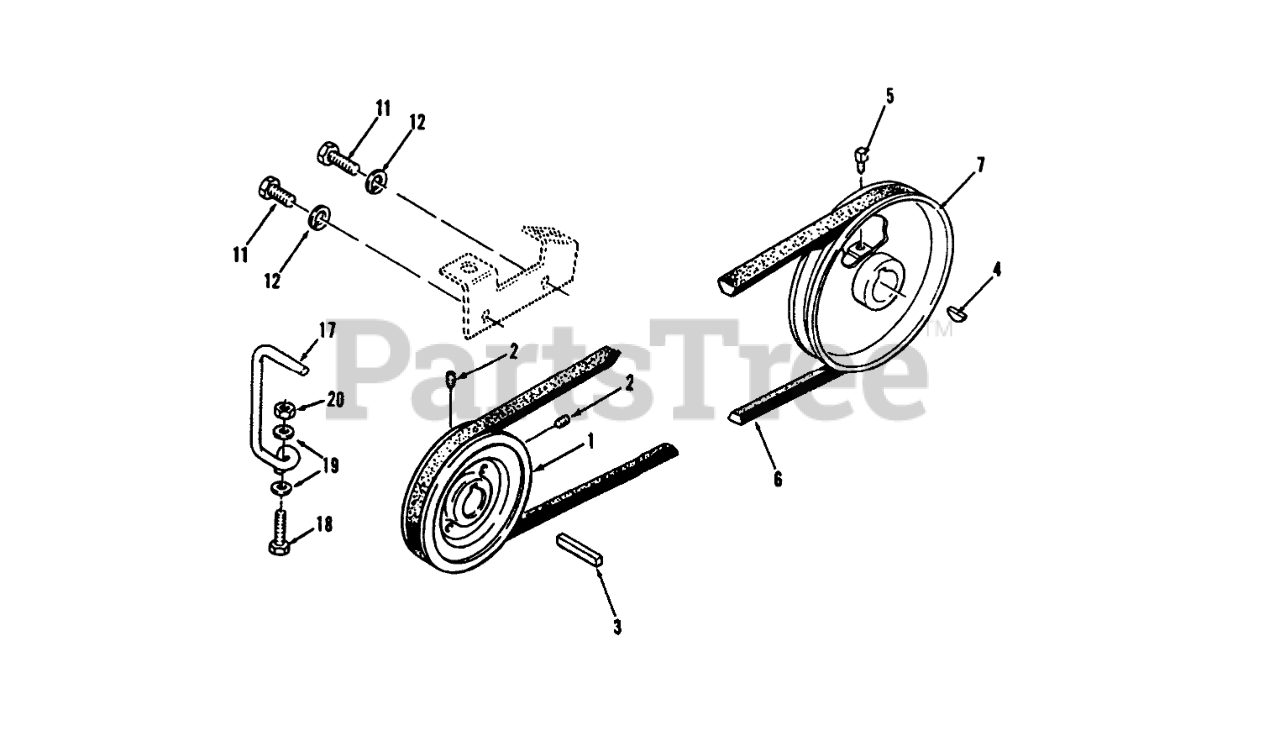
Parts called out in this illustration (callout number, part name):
1	PULLEY
2	SCREW-SET, HSH
4	KEY-HI PRO
5	SCREW-SQH
6	Belt-Drive
7	PULLEY-TRANSMISSION
11	SCREW-HH
12	WASHER-LOCK
17	GUIDE-BELT BOTTOM
18	SCREW-HH
19	WASHER-FLAT
20	NUT-LOCK, NI
